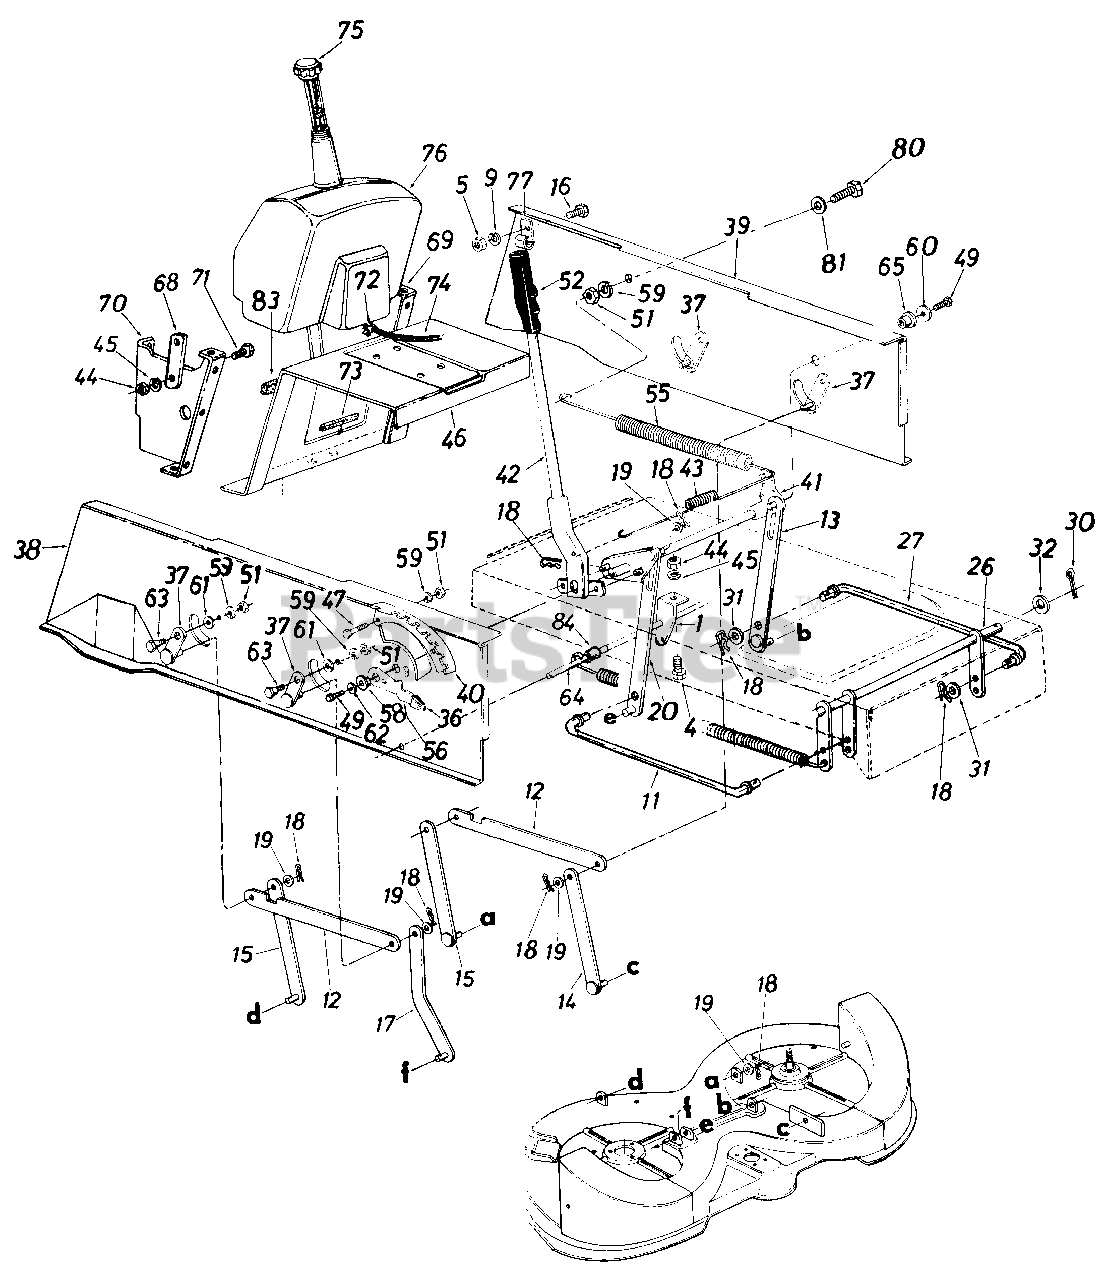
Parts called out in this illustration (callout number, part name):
1	Spring Hanger Bracket
4	Hex Bolt 1/4-20 x .62" Lg.
5	Hex Nut 5/16-18 Thd.*
9	L-Wash. 5/16" I.D.
11	Stabilizer Rod
12	Connecting Rod 3/16 x 1 x 12.5
13	Deck Lift Link Ass'y.
14	Deck Hanger Link Ass'y.-Rear L.H.
15	Deck Hanger Link Ass'y.
16	Hex Bolt 5/16-18 x .75" Lg.
17	Deck Hanger Link Ass'y.-
18	Inter. Cotter Pin 1/2" Dia.
19	Fl-Wash. .531 I.D. x .93" O.D.
20	Deck Lift Link Ass'y.
26	Stabilizer Shaft Ass'y.
27	Stabilizer Rod
30	Cotter Pin 1/8" Dia. x 1.25" Lg.
31	Fl-Wash. .385" I.D. x .620" O.D.
32	Fl-Wash. .635" I.D. x 1.12" O.D.
36	Knob-Height Adj.
37	Pivot Link Ass'y.
38	Side Panel Upper Frame-R.H.
39	Side Panel Upper Frame-L.H.
40	Index Brkt.
41	Lift Shaft Ass'y.
42	Lift Handle Brkt. Ass'y.
43	Ext. Spring .56" I.D. x 32 Coils
44	Hex Nut 1/4-20 Thd.
45	L-Wash. 1/4" I.D.
46	Hitch Plate
47	Hex Bolt 5/16-18 x .75" Lg.
49	Hex Wash. TT-Tap Scr. 5/16-18 x .62" Lg.
51	Hex Nut 5/16-18 Thd.
52	Grip
55	Ext. Spring .99" Dia. x 11.00" Lg.
56	Deck Lift-Down Stop
58	Flange Brg. .630" I.D.
59	L-Wash. 5/16" I.D.*
61	Fl-Wash. .344" I.D. x .62" O.D. x .063
62	Fl-Wash. .344" I.D. x 1.125" O.D.
63	Shld. Bolt .437" Dia. x .180
64	Running Board Rod
65	Flange Brg. .632" I.D.
68	Fender Support Brkt.
69	Grass Catcher Support Brkt. -L.H.
70	Grass Catcher Support Brkt. -R.H.
71	Hex Bolt 1/4-20 x .50" Lg.
72	Hose Clamp-.406" Dia.
73	Trim Strip-5" Lg.
74	Gas Line-44" Lg.
75	Gas Tank Cap
76	Gas Tank
77	Hose Clamp
80	Hex Bolt 5/16-18 x 1.50" Lg.
81	Fl-Wash. .344" I.D. x .875" O.D.
83	Foam Strip 3/8" x 1-1/8" x 11/2" Lg.
84	Spacer .523" I.D. x .640" O.D. x 1.95" Lg.
